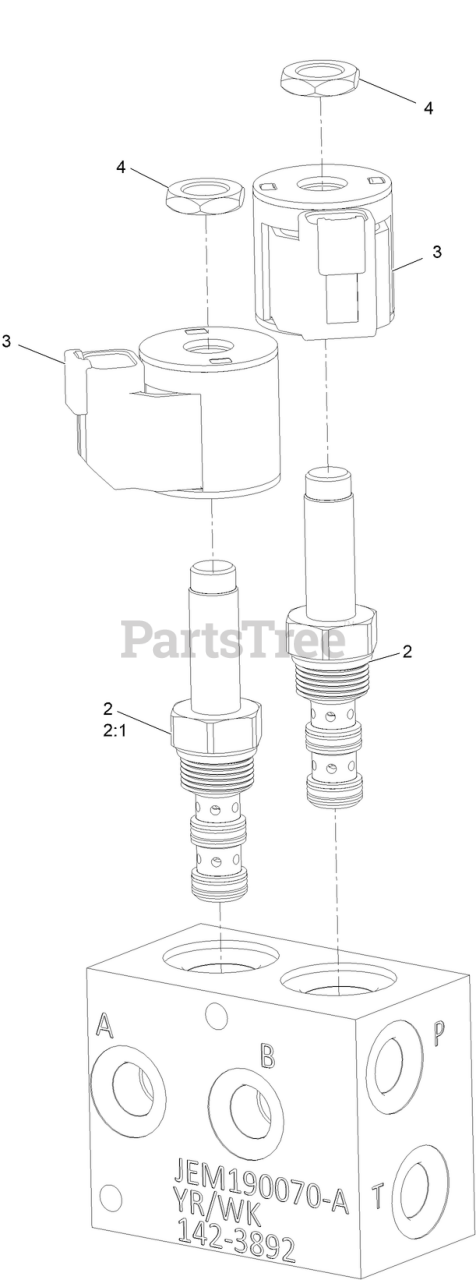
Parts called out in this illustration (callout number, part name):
2	VALVE-3 WAY
2:1	SEAL KIT
4	NUT-COIL
